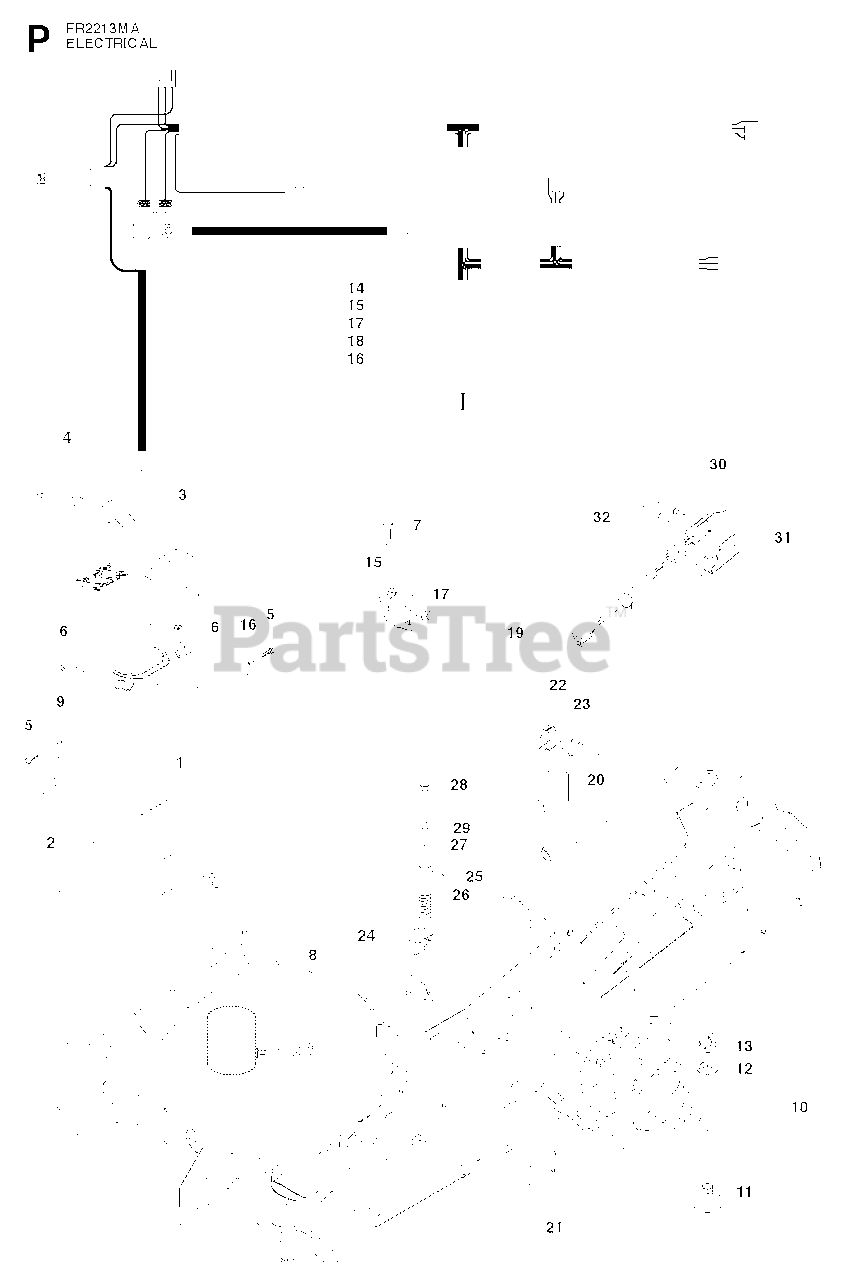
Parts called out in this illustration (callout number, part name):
5	SCREW EHHM
10	IGNITION SWITCH
11	IGNITION SWITCH
12	NUT
13	IGNITION KEY
19	WIRING
27	SPACER TUBE
28	SCREW
29	WASHER BRB 8.4X17
30	MICRO SWITCH
